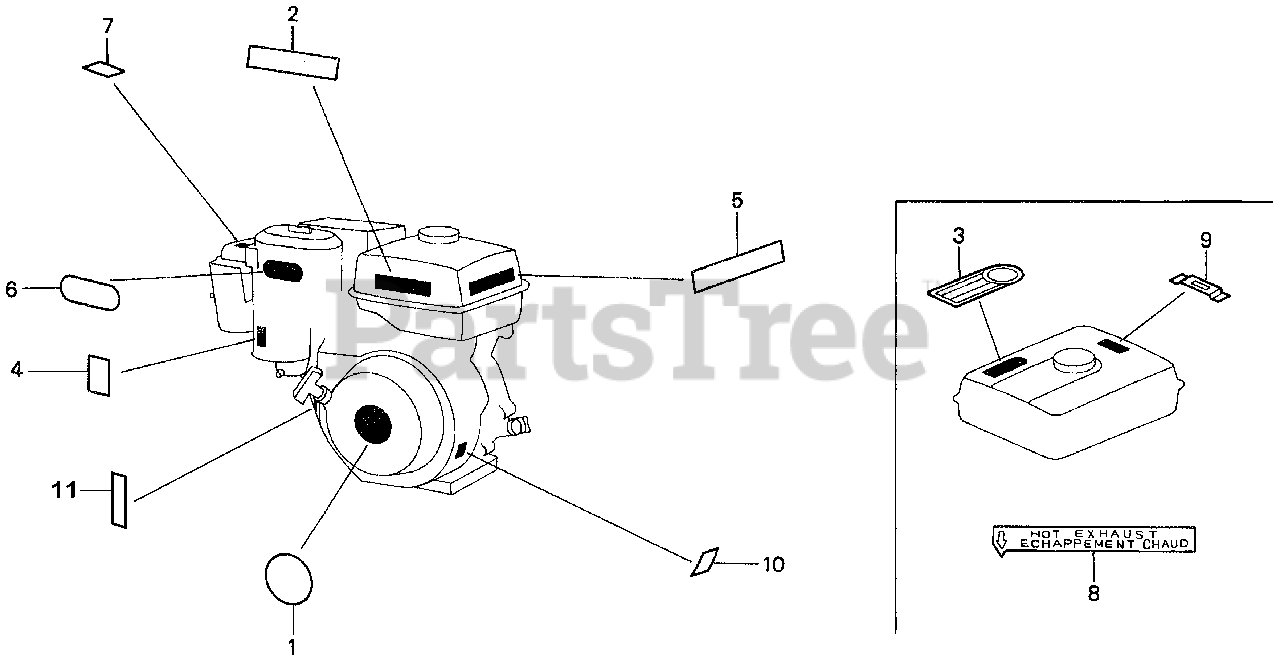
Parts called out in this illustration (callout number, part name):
1	EMBLEM
2	LABEL, CAUTION
4	MARK, CHOKE (EXTERNAL)
5	MARK, OIL ALERT (GERMAN)
5	MARK, OIL ALERT (FRENCH)
5	MARK, OIL ALERT (E)
